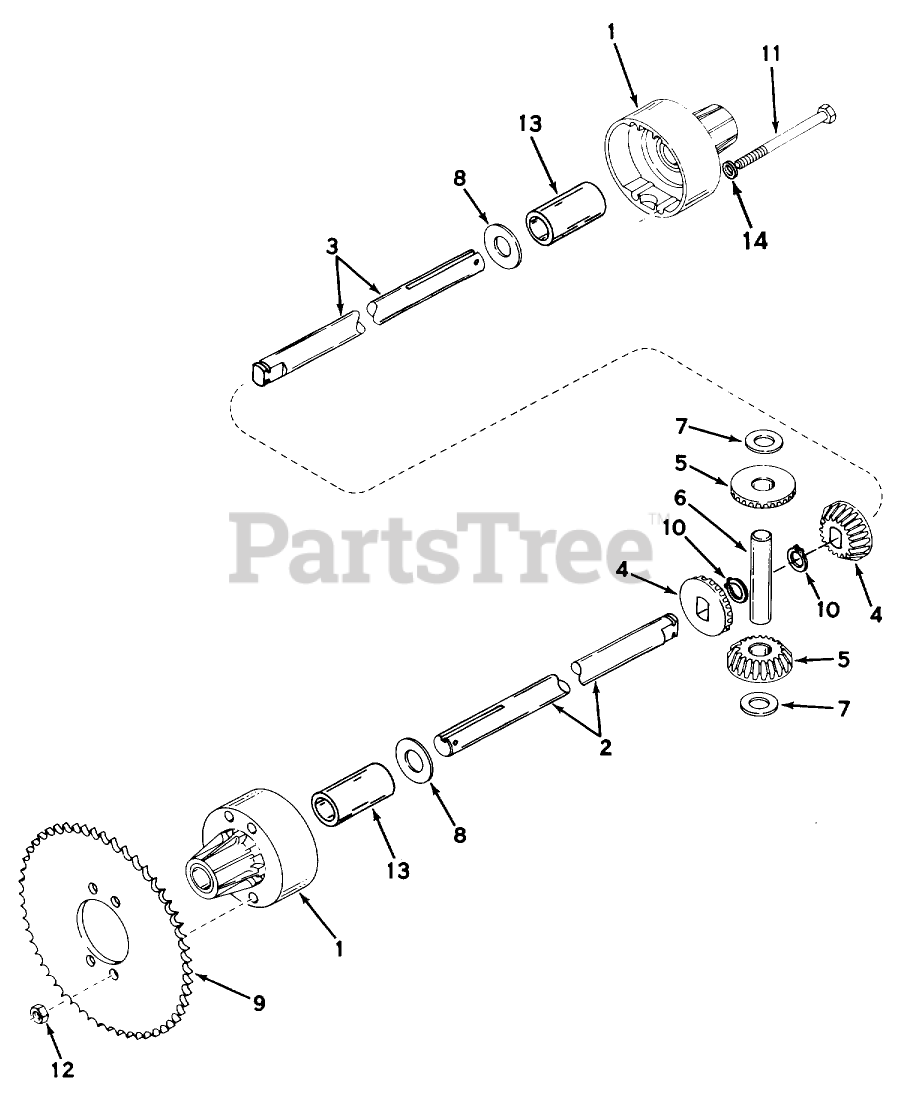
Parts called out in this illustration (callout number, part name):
1	Housing, Differential Carrier
2	Axle (10-29/64" Long)
3	Axle (15-21/46" Long)
4	Bevel Gear
5	Gear Pinion
6	Pin Drive
7	Washer Thrust
8	Washer
9	Sprocket (40 teeth)
10	Snap Ring
11	Screw-Hex Hd.
12	Nut-Lock
13	Bushing
14	Washer
